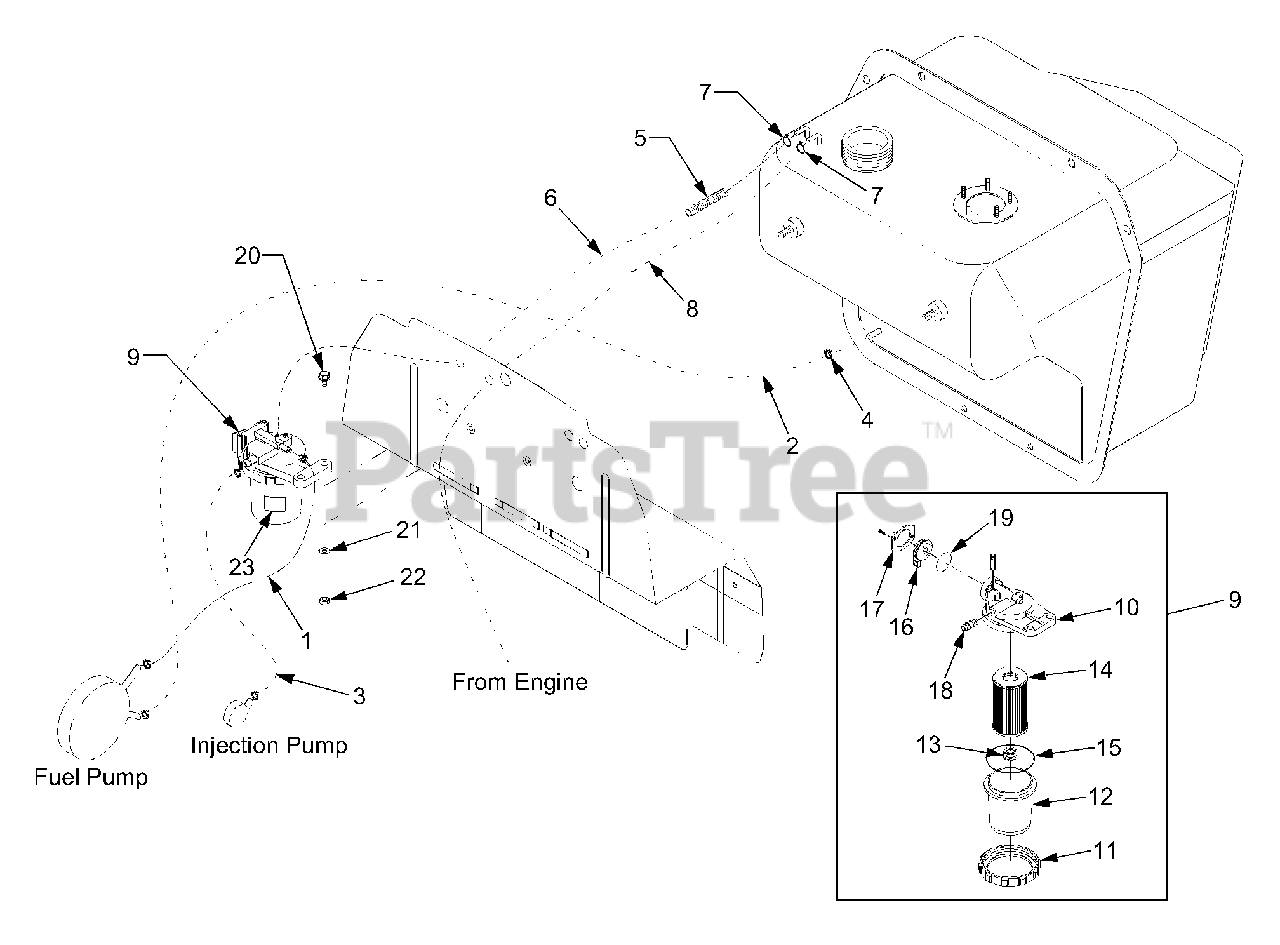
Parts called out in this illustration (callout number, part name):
9	Fuel Filter Ass'y
10	Body, Fuel Filter
12	Pot, Filter
14	Element, Filter
17	Support, Handle
21	Washer, Spring
23	Label (Fuel Filter)
